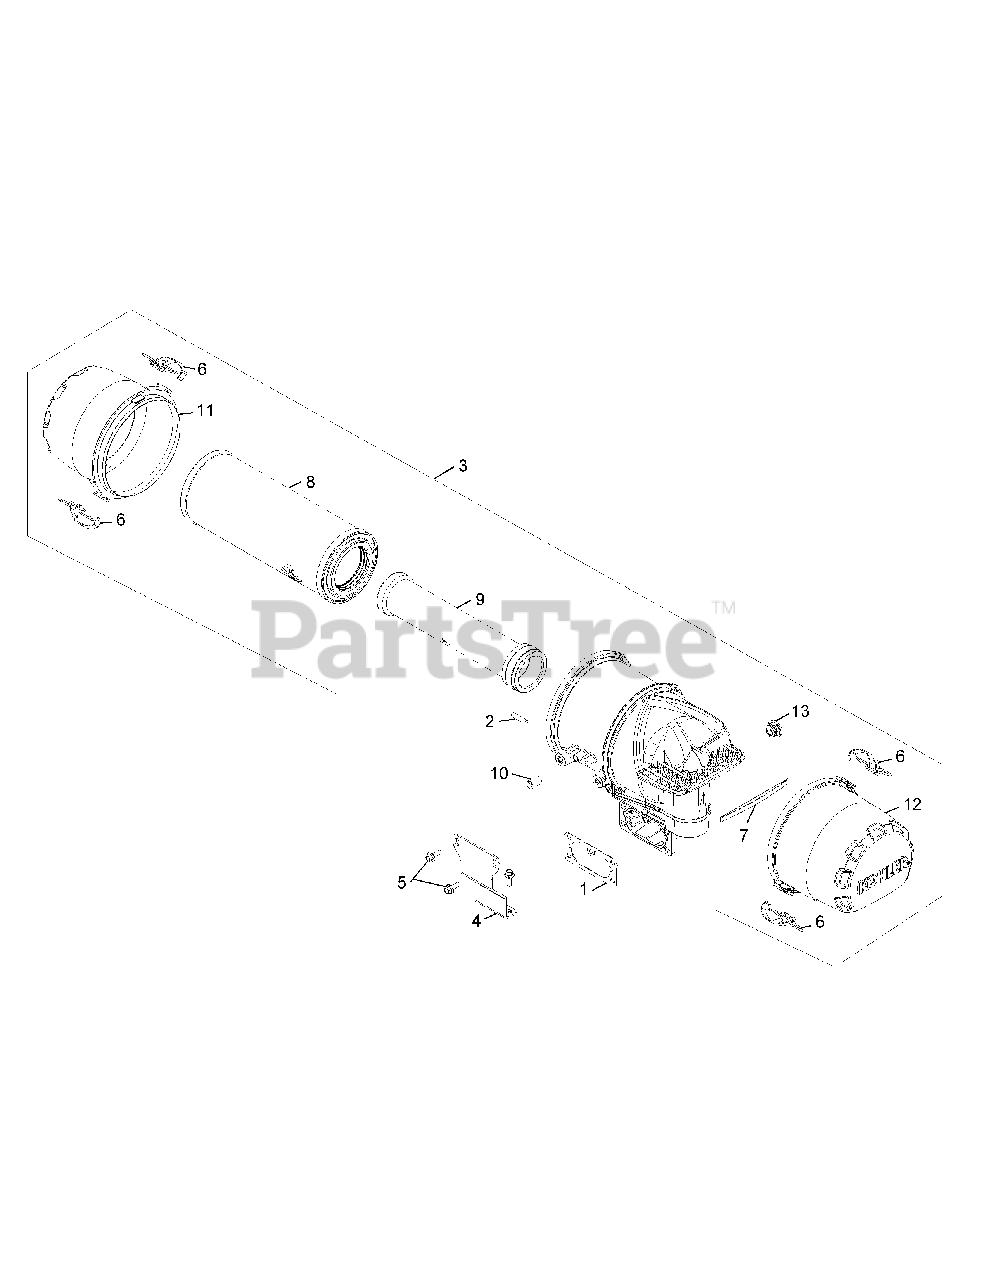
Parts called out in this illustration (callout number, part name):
1	Air Cleaner Gasket
3	Air Cleaner Kit
4	Support Bracket
5	Flange Screw, M6 x 1.0 x 16
6	Assembly Clip
7	Foam Insert Damper
8	Element, Air Filter - PRIMARY
9	Element, Air Filter - SAFETY
11	Air Filter Cover
12	Rain Cap Cover
